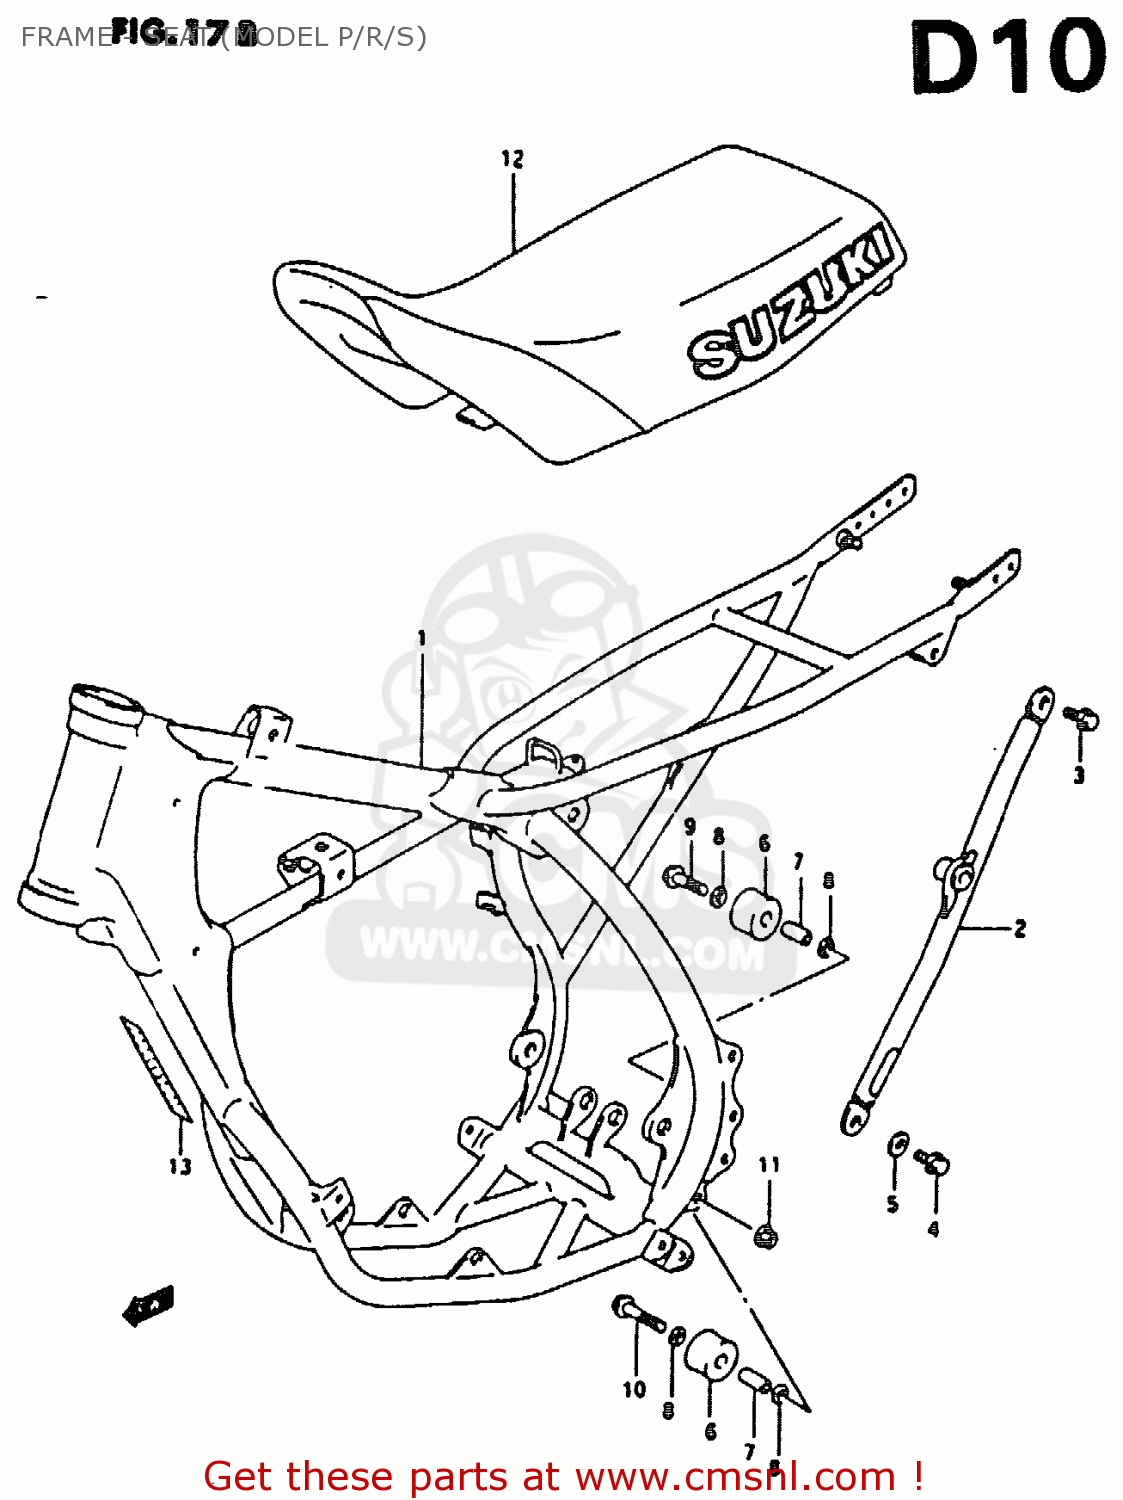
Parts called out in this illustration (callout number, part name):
1	FRAME
2	TUBE,FRAME SIDE(CHARCOAL)
3	BOLT(8X22)
4	BOLT(8X16)
5	WASHER
6	ROLLER,CHAIN CONTROL
7	SPACER
8	WASHER
9	BOLT(8X41)
10	BOLT(6X20)
11	NUT
12	SEAT SET
13	PLATE,WARNING
14	BOLT
15	WASHER
16	NUT
17	SEAT ASSEMBLY
18	TOOL SET
